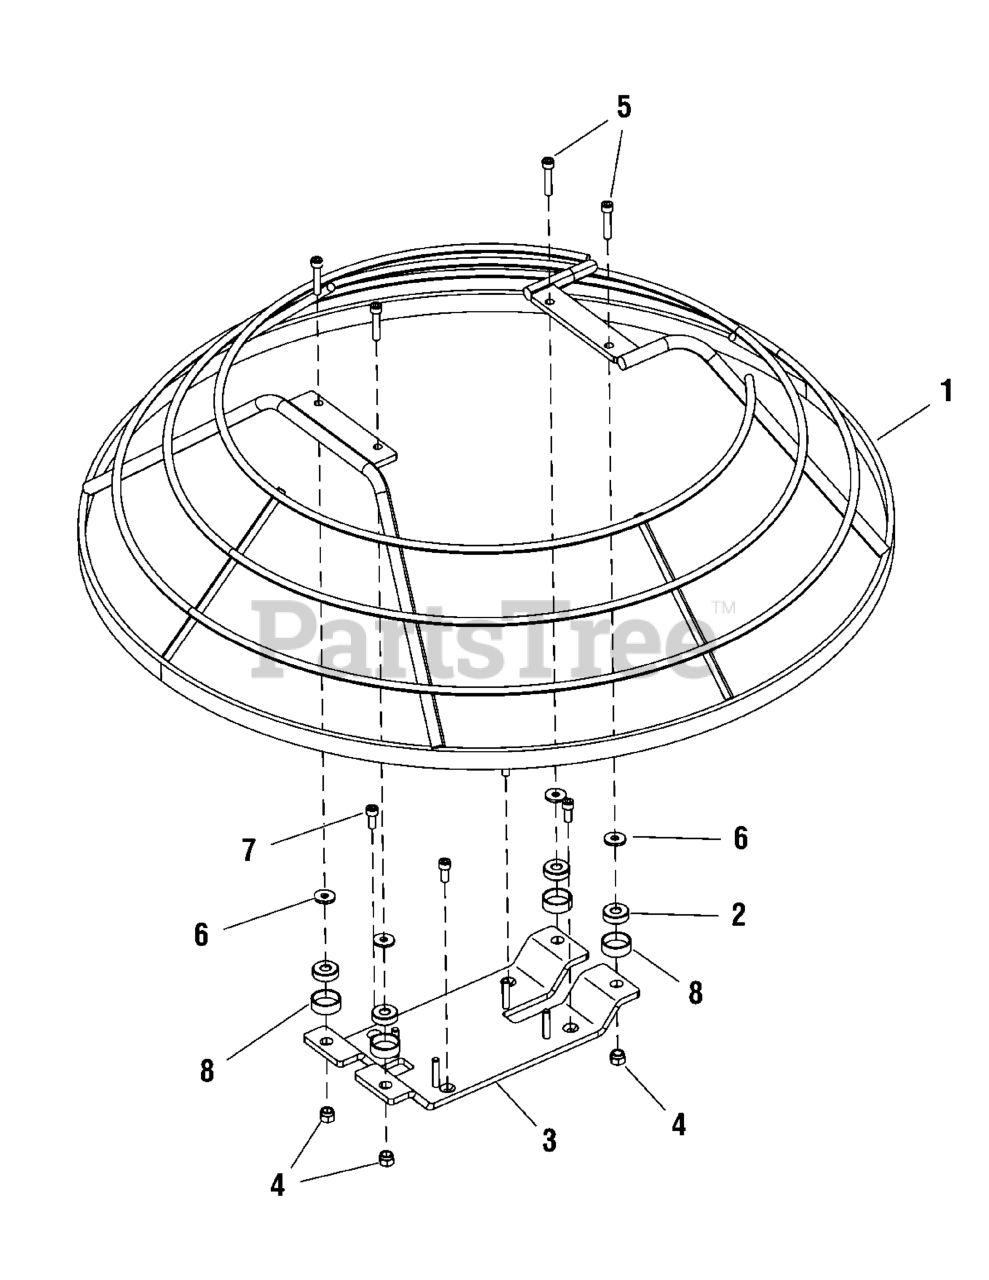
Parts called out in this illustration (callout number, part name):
1	BLADE HOUSING
2	PAD, Vibration
3	BRACKET, Engine
4	NUT, Hex Flange, M8
5	BOLT, Hex Socket Head, M8 x 40
6	WASHER, Flat
7	BOLT, Hex Socket Head, M8 x 20
8	COVER, Vibration Pad
